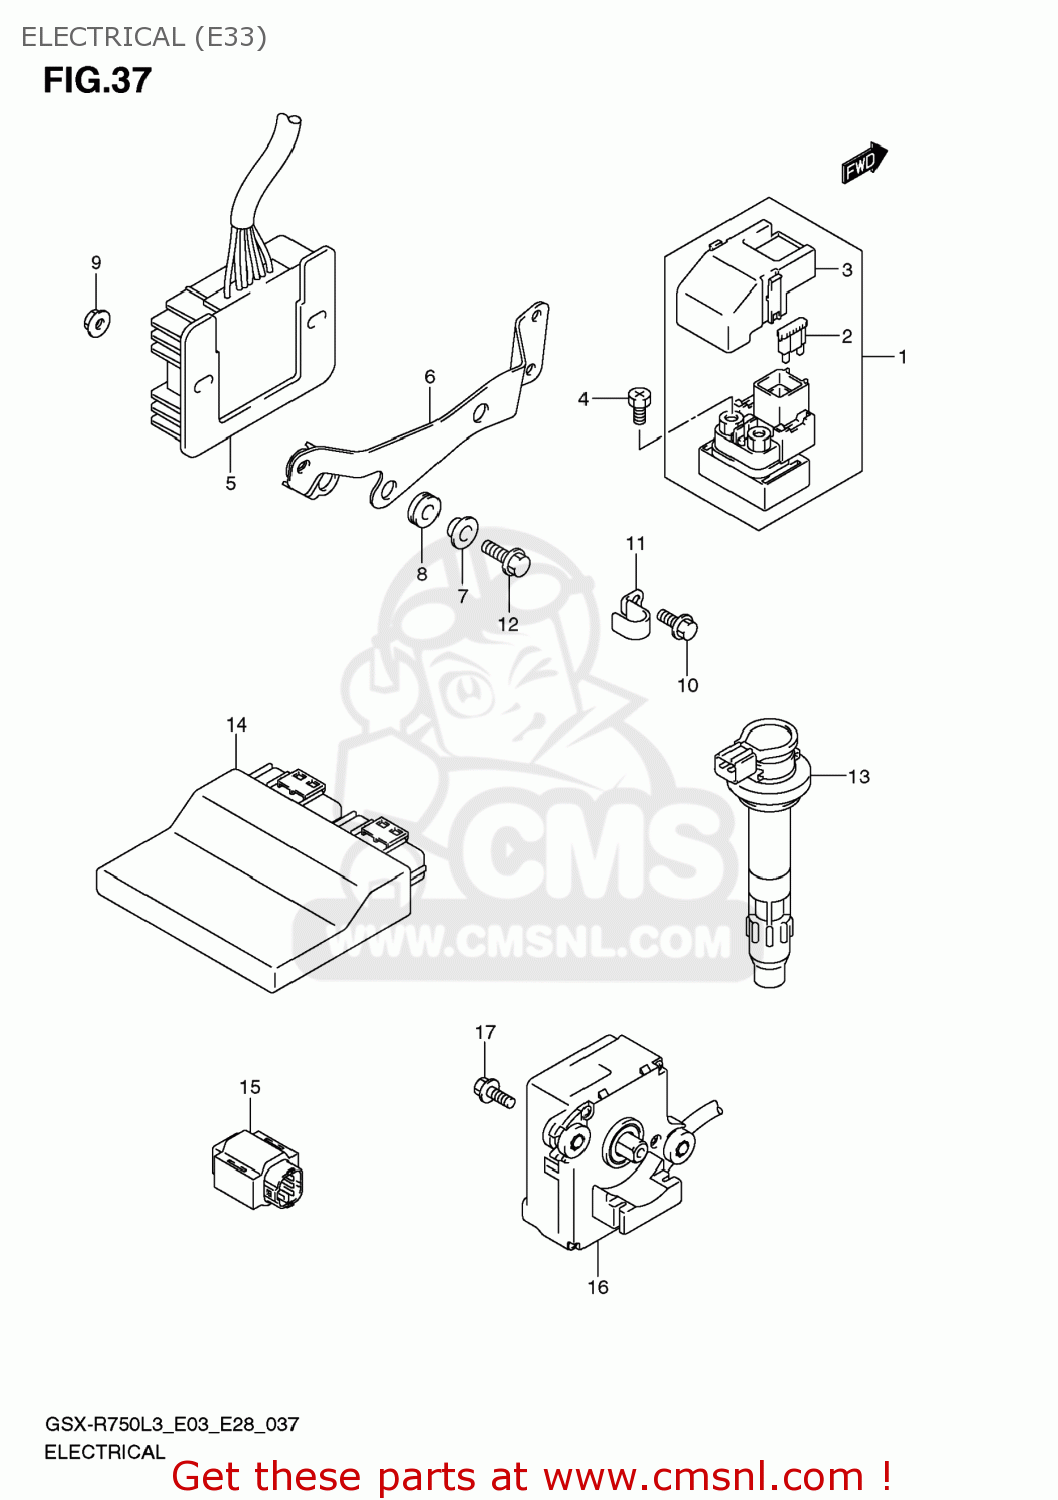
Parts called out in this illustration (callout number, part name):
1	RELAY ASSY,STARTING MOTOR
2	FUSE(30A)
3	COVER
4	SCREW(6X8)
5	RECTIFIER ASSY
6	BRACKET,RECTIFIER
7	SPACER(6.2X8.4X6.9)
8	CUSHION
9	BOLT(6X20)
10	BOLT
11	CLAMP(L:80)
12	NUT
13	COIL ASSY,IGNITION
14	CONTROL UNIT,FI
15	SENSOR ASSY,FUEL CUT
16	ACTUATOR ASSY,EXHAUST CONTROL
17	BOLT(6X32.5)
